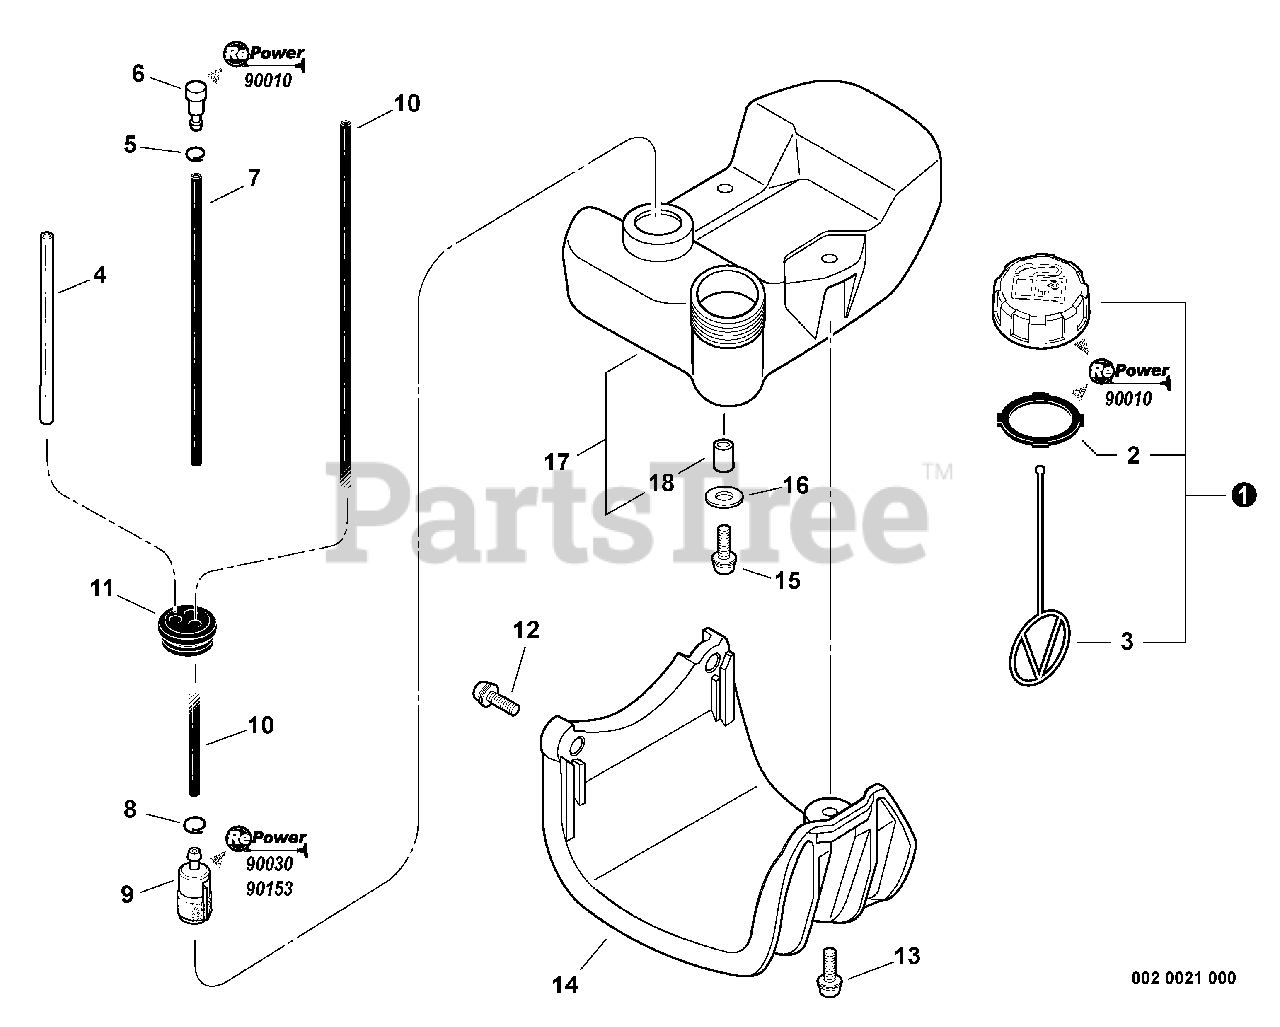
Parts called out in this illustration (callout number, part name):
1	CAP ASSY, FUEL
2	GASKET, FUEL CAP
3	CONNECTOR, CAP L= 100 MM
4	PIPE, FUEL 3×6×80 CLEAR
5	CLIP Ø6.5 MM
6	VENT ASSY
7	PIPE 3×6×115 BLACK
8	CLIP Ø6.5 MM
9	FILTER, FUEL
10	PIPE, FUEL 3×6×170
11	GROMMET, FUEL
12	BOLT 5×22
13	SCREW 5×20
14	GUARD, FUEL TANK
15	BOLT 5×16
16	WASHER 5.5×12×0.8
17	TANK, FUEL
18	SPACER 6.2×7.8×6
19	CAP/VENT KIT - REPOWER
20	REPOWER FILTRATION KIT
21	TUNE-UP KIT
